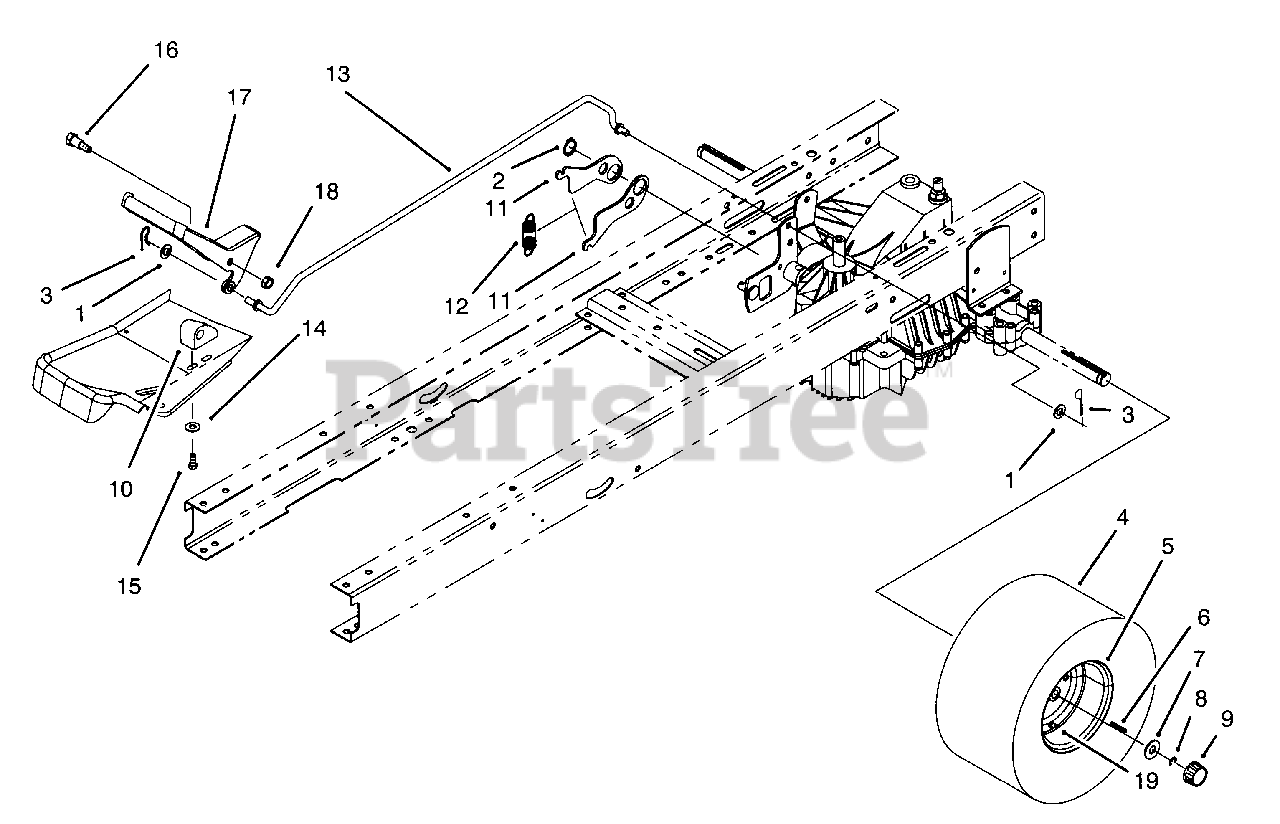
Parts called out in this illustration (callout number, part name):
1	Washer-Flat
2	Ring-External Retaining
3	Pin-Cotter
6	Key-Square
10	Block-Pivot
11	Lever-Neutral Control
12	Spring-Extension
13	Rod-Speed Control
14	Washer-Flat
15	Screw-Plastite
16	Bolt-Shoulder
17	Pedal-Speed Control
18	Nut-Lock
19	Valve Stem w/Cap
